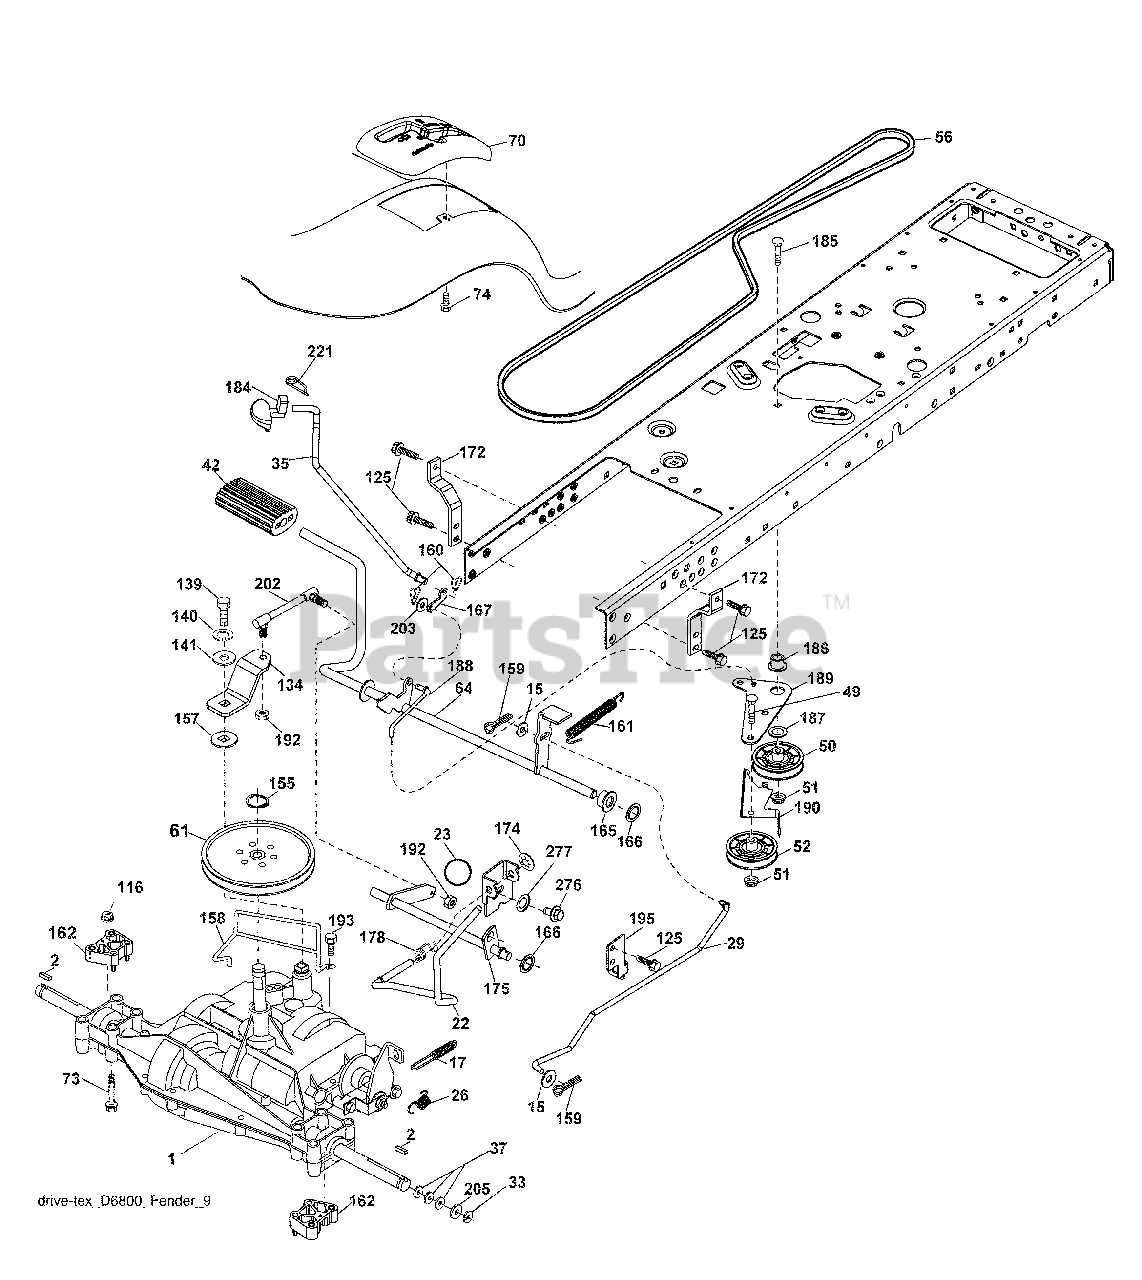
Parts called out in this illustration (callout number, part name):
2	Key Square
15	Washer 13/32 x 13/16 x 16 Ga.
17	Spring, Brake
23	Knob Duckhead 1/2-13
26	Spring Brake Return
29	Rod, Brake
35	Rod, Brake, Park
37	Washer 25/32 x 1-1/4 x 16 Ga.
42	Cover, Foot Pedal
50	Pulley Idler Flat
51	Lock Nut 3/8-16
52	Idler V-Groove
56	V-Belt, Drive
61	Pulley Transaxle
64	Shaft Asm. Pedal Brake Control
70	Console
74	Screw 1/4 x 1/2
116	Nut Lock Hex Flange 5/16-18
125	Screw 5/16-18 x 3/4
139	Bolt 1/4-28 unf Gr. 8 w/Patch
140	Washer Lock Hvy Helical 1/4
141	Washer 9/32 x 3/4 x 10 Ga.
155	Ring Retainer
157	Washer Plate Shift
158	Belt Keeper
159	Pin Cotter 1/8 x 3/4
160	Retainer Clip
161	Spring, Return, Clutch
162	Spacer Transaxle
165	Bushing Shaft Brake Hand Control
166	Nut Push .625
167	Latch Brake Parking
172	Strap Torque LH
175	Shaft Asm. Shift
178	Spring Shift
184	Knob
186	Spacer Retainer
187	Washer
188	Link Clutch Ground Drive
189	Bellcrank Ground Drive
190	Keeper Bellcrank Ground Drive
192	Nut Lock Center 1/4-28 Fnthd
193	Screw 5/16-18 x 3/4
195	Bracket Brake Rod
202	Link Transaxle
203	Washer 11/32 x 11/16 x 16 Ga.
205	Washer 25/32 x 1-5/8 16 Ga.
216	Bracket Pulley Idler
221	Retainer Spring Clip Handle
225	Bolt 5/16-18 x 3.75
276	Bolt Fin Hex 7/16-14 x 1 Gr. 5
277	Washer Serrated
